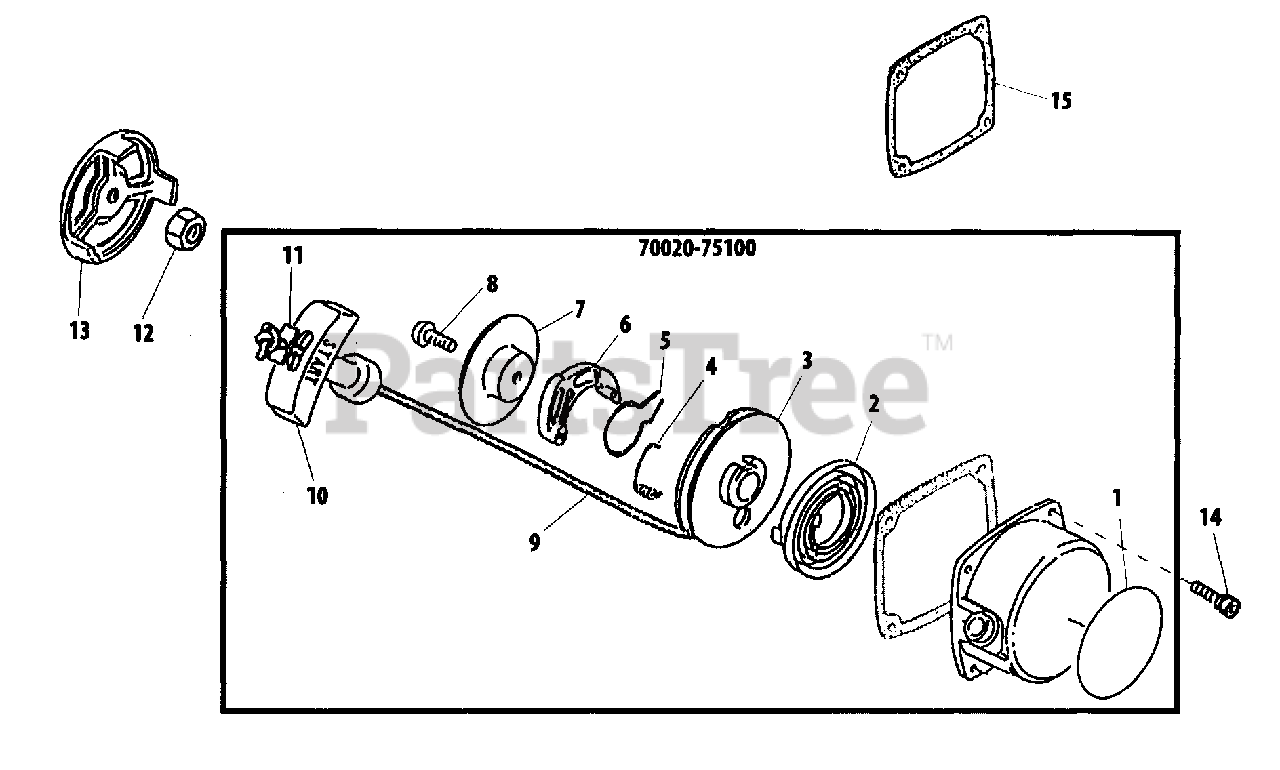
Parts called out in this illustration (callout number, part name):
1	LABEL - MODEL
2	SPRING, REWIND
3	REEL, ROPE
4	SPRING, RETURN
5	SPRING
6	PAWL, STARTER
7	PLATE, STARTER
8	SCREW
9	ROPE
10	GRIP, STARTER
11	RETAINER, ROPE
12	NUT - 8
13	CATCHER, STARTER
14	SCREW - 4X16
15	GASKET
70020-75100	STARTER ASSY
